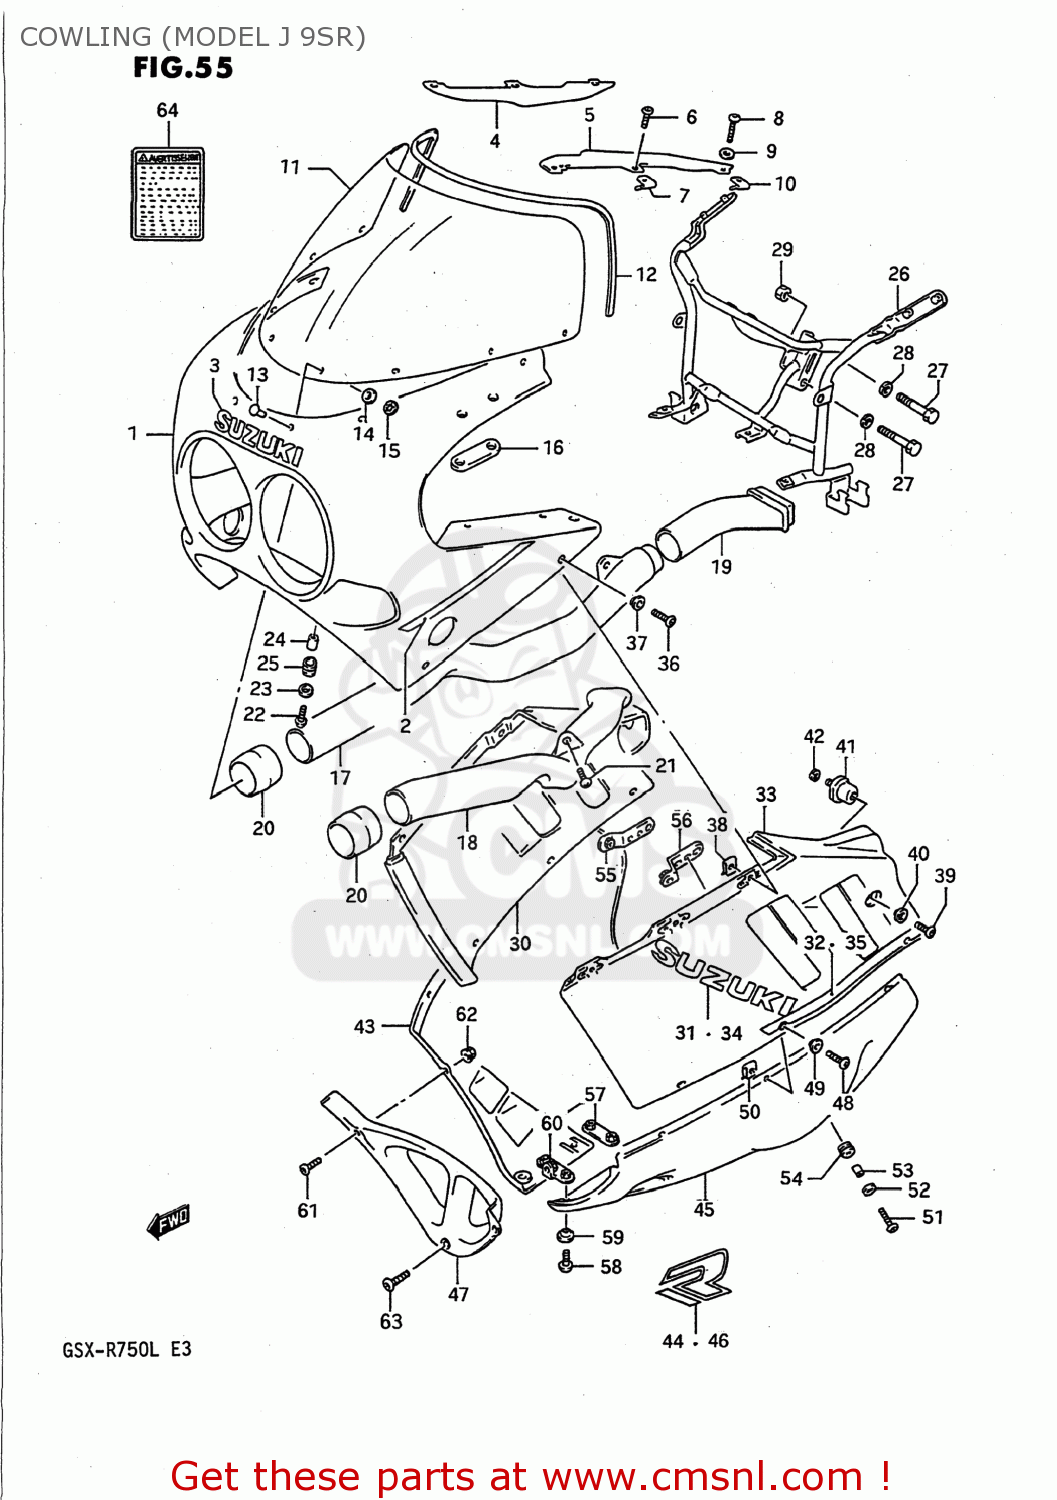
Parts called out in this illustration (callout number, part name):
1	BODY ASSEMBLY,COWLING
2	TAPE SET,COWLING
3	EMBLEM,COWLING,UPPER (W)
4	PANEL,COWLING UPPER,RIGHT
5	COVER,COWLING,LEFT
6	SCREW(5X10)
7	NUT
8	SCREW(5X14)
9	WASHER(5.2X11X1)
10	NUT
11	WINDSCREEN
12	MOLDING,WINDSCREEN
13	PIN,WINDSCREEN
14	CUSHION
15	NUT
16	CUSHION,RR VIEW MIRRORR
17	PIPE,AIR INTAKE,FRONT
18	PIPE,AIR INTAKE,FRONT
19	PIPE,AIR INTAKE RR,R
20	JOINT,AIR INTAKE
21	SCREW
22	SCREW(6X20)
23	WASHER(6.5X18X1)
24	SPACER
25	CUSHION
26	BRACE,COWLING
27	BOLT
28	WASHER,LOCK,8.
29	NUT ,8MM
30	COVER,COWLING SIDE,RIGHT
31	EMBLEM
32	TAPE,COWLING SIDE STRIPE
33	COVER,COWLING SIDE,LEFT
34	EMBLEM
35	TAPE,COWLING SIDE STRIPE
36	SCREW(5X18)
37	WASHER(5.2X14X1.5)
38	NUT,HEADLAMP HOUSING,UPPER
39	SCREW(6X12)
40	WASHER(6.3X16X1.5)
41	CUSHION,COWLING
42	WASHER,LOCK
43	COWLING COMP,UNDER,RIGHT
44	EMBLEM,COWLING UNDER
45	COWLING COMP,UNDER,LEFT
46	EMBLEM,COWLING UNDER
47	COWLING,UNDER,CENTER
48	SCREW(5X18)
49	WASHER(5.2X14X1.5)
50	NUT,HEADLAMP HOUSING,UPPER
51	SCREW(6X20)
52	WASHER(6.5X18X1)
53	SPACER
54	CUSHION
55	BRACKET
56	BRACE,COWLING UNDER,LH
57	BRACE,COWLING LWR COVER RR
58	SCREW(6X16)
59	WASHER(6.3X16X1.5)
60	BRACE,COWLING LWR COVER
61	SCREW(5X14)
62	NUT
63	SCREW(6X16)
64	LABEL (WARNING SCREEN)
